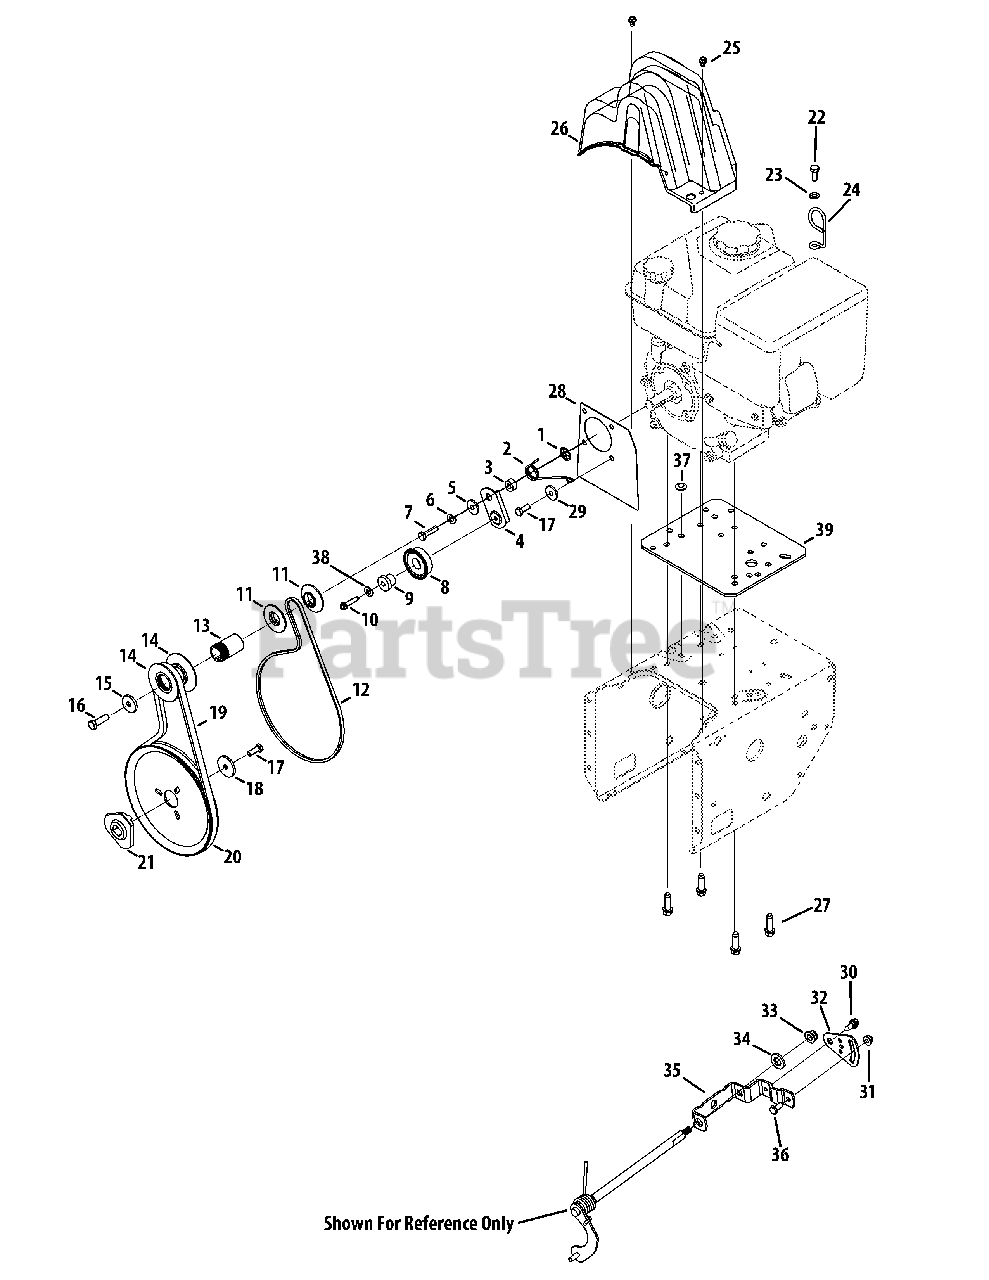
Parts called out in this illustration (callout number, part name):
1	Push-On Nut
2	Torsion Spring, .850 ID x .333
3	Spacer, .340 x .750 x .330
4	Idler Bracket
5	Shldr. Spacer, .3175 ID x .500 x .0975
6	Lock Washer, 5/16
7	Hex Screw, 5/16-24 x 1.25
8	Idler Pulley
9	Shoulder Spacer, .260 x .785 x .538
10	Hex Washer Screw, 1/4-20 x 1.250
11	Pulley Half, 3/8-V x 1.7160 OD
13	Spacer, .875 ID x 1.185 OD
14	Pulley Half, 4L-V x 2.600 OD
15	Flat Washer, .406 x 1.25 x .157
16	Hex Screw, 3/8-24 x 1.25
17	Hex Lock Screw, 5/16-24 x .875
18	Flat Washer, .34 x 1.50 x .150
19	Belt
20	Auger Pulley
21	Adapter Pulley
22	Hex Screw, M8-1.25 x 20
23	Flat Washer, .330 x .630 x .0635
24	Cable Control Wire
25	Hex Washer Screw, 1/4-20 x .375
26	Belt Cover
27	Hex Washer Screw, 3/8-16 x 1.250
28	Cover Plate
29	Shoulder Spacer
30	Shoulder Screw, .368 x .113 x 1/4-20
31	Flange Lock Nut, 1/4-20
32	Speed Selector Pivot Bracket
33	Flange Lock Nut, 5/16-18
34	Flat Washer, .469 x .875 x .105
35	Speed Selector Shift Bracket
36	Hex Screw, 1/4-20 x .620
37	Plug, 3/8 ID
38	Lock Washer, 1/4
39	Engine Plate
